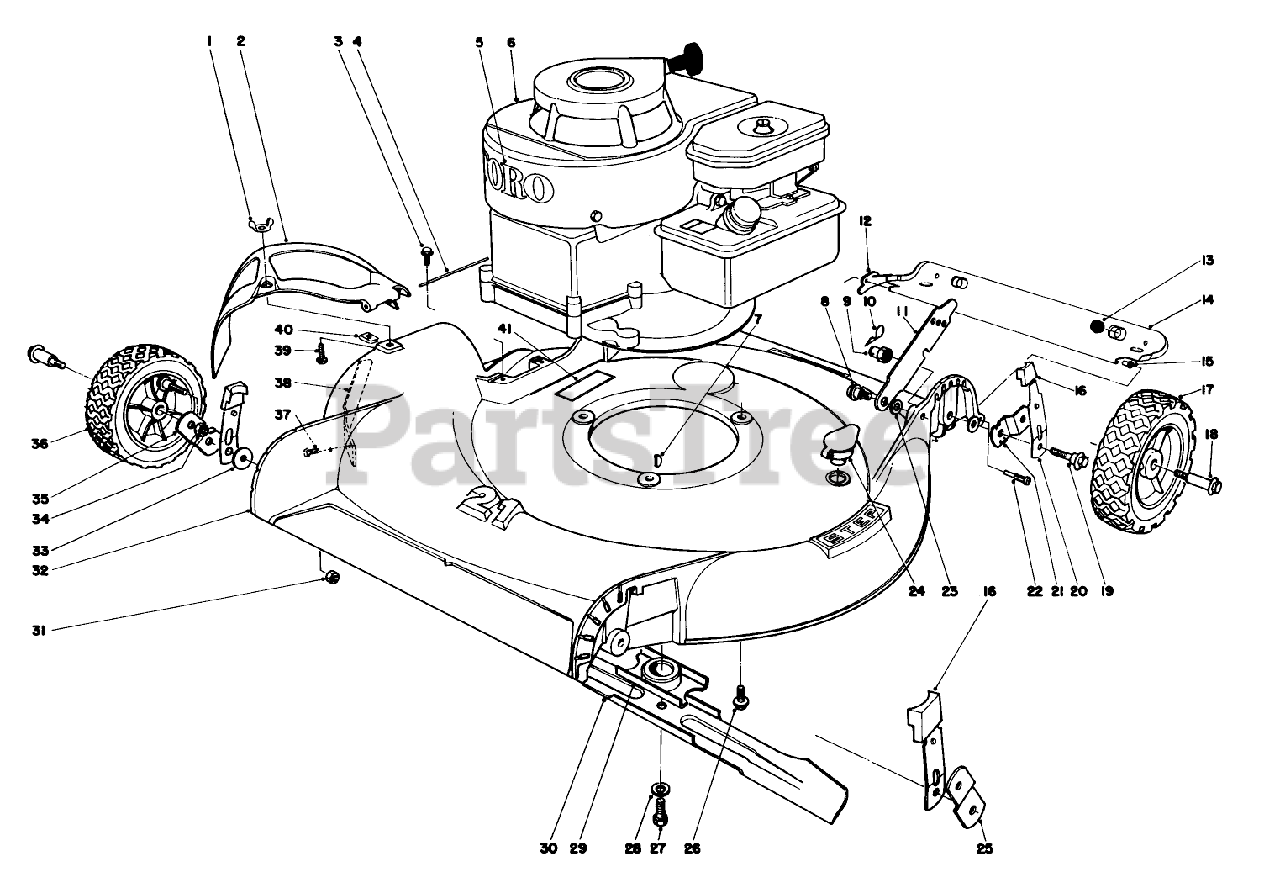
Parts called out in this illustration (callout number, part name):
1	NUT-WING SPECL
3	SCREW
6	Engine
7	KEY-WOODRUFF
8	SCREW-SHOULDER
9	HANDLE PIVOT NUT
10	PIN-COTTER, HAIR
19	PIVOT SCREW
21	PIVOT ARM PLATED
23	SPACER
24	WASHOUT PLUG
28	WASHER-LOCK
32	Housing
33	WASHER-PIVOT
35	PIVOT ARM D PLTD
37	SCREW-HWH
